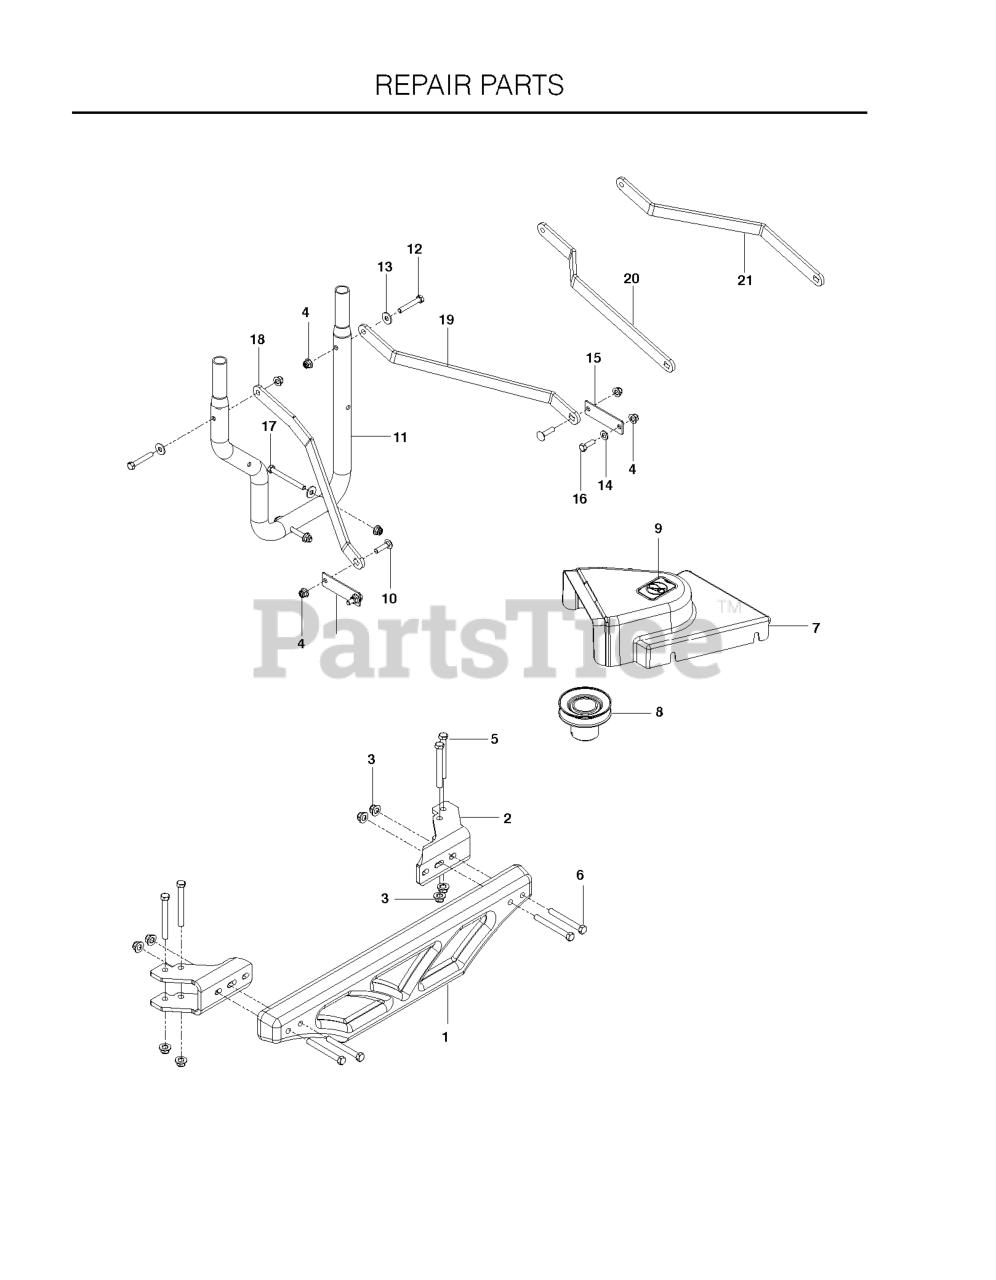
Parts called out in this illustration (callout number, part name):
1	CAST WEIGHT
2	BRACKET WEIGHT BLK
3	NUT 3/8-16 HEX FLG NYLOC ZD
4	5/16-18 NYLOC FLANGE NUT
5	HCS 3/8-16 X 3-1/2 GR5 ZD
6	HCS 3/8C X 3
7	SHIELD, BELT, 48"
8	PULLEY, 42/48"
9	DECAL, NO STEP
10	BOLT, CARRIAGE 5/16X1-1/4
11	MOUNT.TUBE.COLLECTIONS
12	HCS 5/16-18X2
13	WASHER 5/16 FLAT
14	FLAT WASHER 5/16 SAE
15	REINFORCEMENT PLATE BLK
16	HCS 5/16C X 1
17	HCS 5/16-18 X 3 1/4
18	STRAP, SUPPORT, RT PTD
19	STRAP, SUPPORT, LT PTD
20	STRAP, SUPPORT, RT BLK
21	STRAP, SUPPORT, LT BLK
